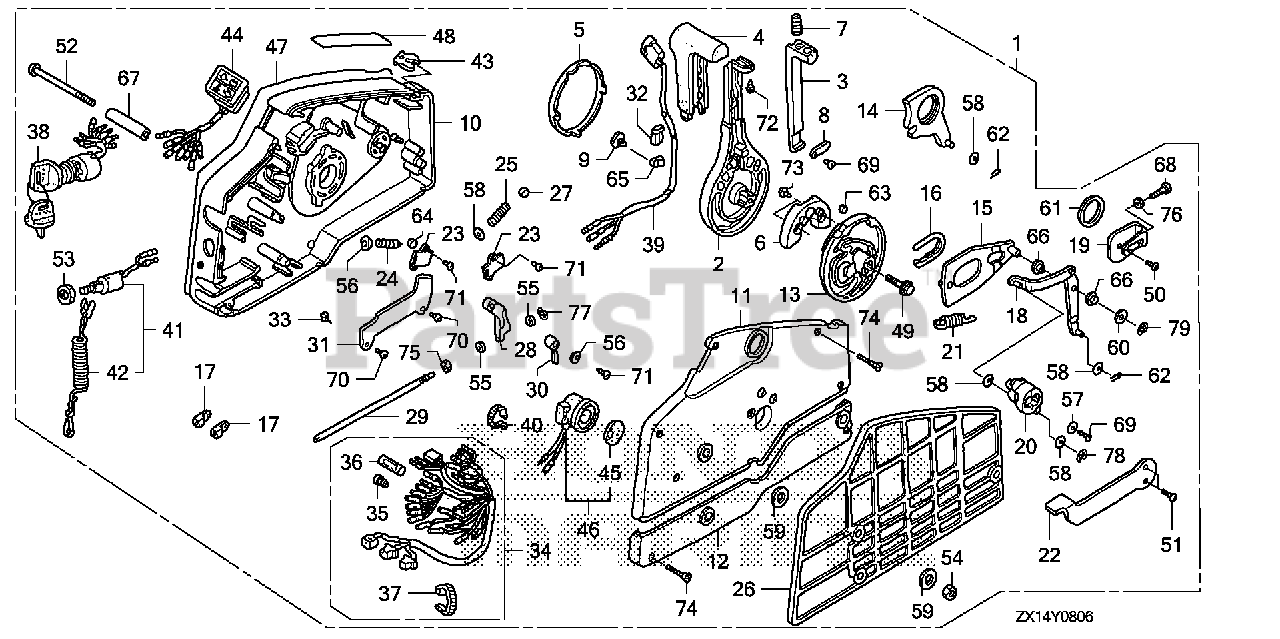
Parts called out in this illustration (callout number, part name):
1	BOX ASSY., REMOTE CONTROL (TROLLING CONTROL)(NHK MEC)
2	HANDLE, REMOTE CONTROL
3	LEVER, HANDLE LOCK
4	GRIP, REMOTE CONTROL HANDLE
5	CAP, HANDLE
6	BLOCK, NEUTRAL LOCK
7	SPRING, REMOTE CONTROL HANDLE
8	PLATE, LEVER SETTING
9	CLAMP, HARNESS
10	HOUSING, REMOTE CONTROL BOX (A)
11	HOUSING, REMOTE CONTROL BOX (B)
12	HOUSING, REMOTE CONTROL BOX (C )
13	WHEEL, CONTROL
14	ARM, SHIFT LINK
15	PLATE, SLIDING
16	COLLAR, SLIDING PLATE
17	PIVOT, SHIFT
18	ARM, LINK JOINT
19	BRACKET, LINK JOINT
20	WHEEL, ACCELERATOR
21	SPRING, ACCELERATOR WHEEL
22	LEVER, IDLE
23	PLATE, SPRING SETTING
24	SPRING, SHIFT CLICK
25	SPRING, CHOKE RETURN
26	SPACER, REMOTE CONTROL BOX
27	SPACER, CLICK SPRING
28	BLOCK, THROTTLE FRICTION
29	BOLT, FRICTION
30	SPACER, NEUTRAL SWITCH
31	CLAMP, POWER TILT CORD
32	PIPE, HARNESS GUIDE
33	SPACER, CABLE CLAMP
34	CABLE ASSY., REMOTE CONTROL (B) (FOR 4-LED)
35	PLUG, CONNECTOR (INNER) (TROLLING CONTROL)
36	PLUG, CONNECTOR (OUTER) (ENGINE NO.)
37	TIE, CABLE (NATURAL 2.4X92) Use up to Frame SN 1300359.
38	SWITCH ASSY., COMBINATION (SINGLE) (DUAL)
39	SWITCH ASSY., POWER TRIM-TILT
40	BAND (BLACK 3.5X140)
41	SWITCH ASSY., EMERGENCY STOP
42	WIRE, EMERGENCY (SINGLE) (DUAL)
43	CLIP, EMERGENCY LOCK
44	LAMP ASSY., INDICATION
45	PLATE, TURN SIGNAL BUZZER DUAL QTY = (2) (SINGLE)
46	BUZZER, WARNING DUAL QTY = (2) (SINGLE)
47	PLATE, REMOTE CONTROL (COUTION COLOR=RED & YELLOW)
48	MARK, FAST IDLE
49	BOLT, FLANGE (8X35) Use from Frame SN 4800713.
50	SCREW, PAN (6X10)
51	SCREW, FLAT (5X12) Use from Frame SN 4800713.
52	SCREW (6X95)
53	NUT, HEX. (16MM) DUAL QTY = (2) (SINGLE)
54	NUT, HEX. (6MM)
55	WASHER, PLAIN (4MM) Use from Frame SN 4800713.
56	WASHER, PLAIN (5MM)
57	WASHER, PLAIN (5MM)
58	WASHER, PLAIN (6MM) Use from Frame SN 4800713.
59	WASHER (6MM)
60	WASHER, PLAIN (8MM) Use from Frame SN 4800713.
61	WASHER (28MM)
62	PIN, LOCK (6MM)
63	PIN (6X6)
64	ROLLER, CLICK
65	CLIP, WIRE HARNESS (6.3MM)
66	COLLAR, LINK JOINT
67	COLLAR, DISTANCE (6X10X43.5)
68	BOLT, HEX. (5X16)
69	SCREW, PAN (5X10)
70	SCREW, TAPPING (5X8) (FOR SILVER MUFFLER)
71	SCREW, TAPPING (5X10)
72	SCREW, TAPPING (5X12)
73	SCREW, TAPPING (6X16)
74	SCREW, TAPPING (5X25)
75	NUT, HEX. (6MM)
76	NUT, HEX. (5MM)
77	E-RING (3MM)
78	E-RING (4MM)
79	E-RING (7MM)
